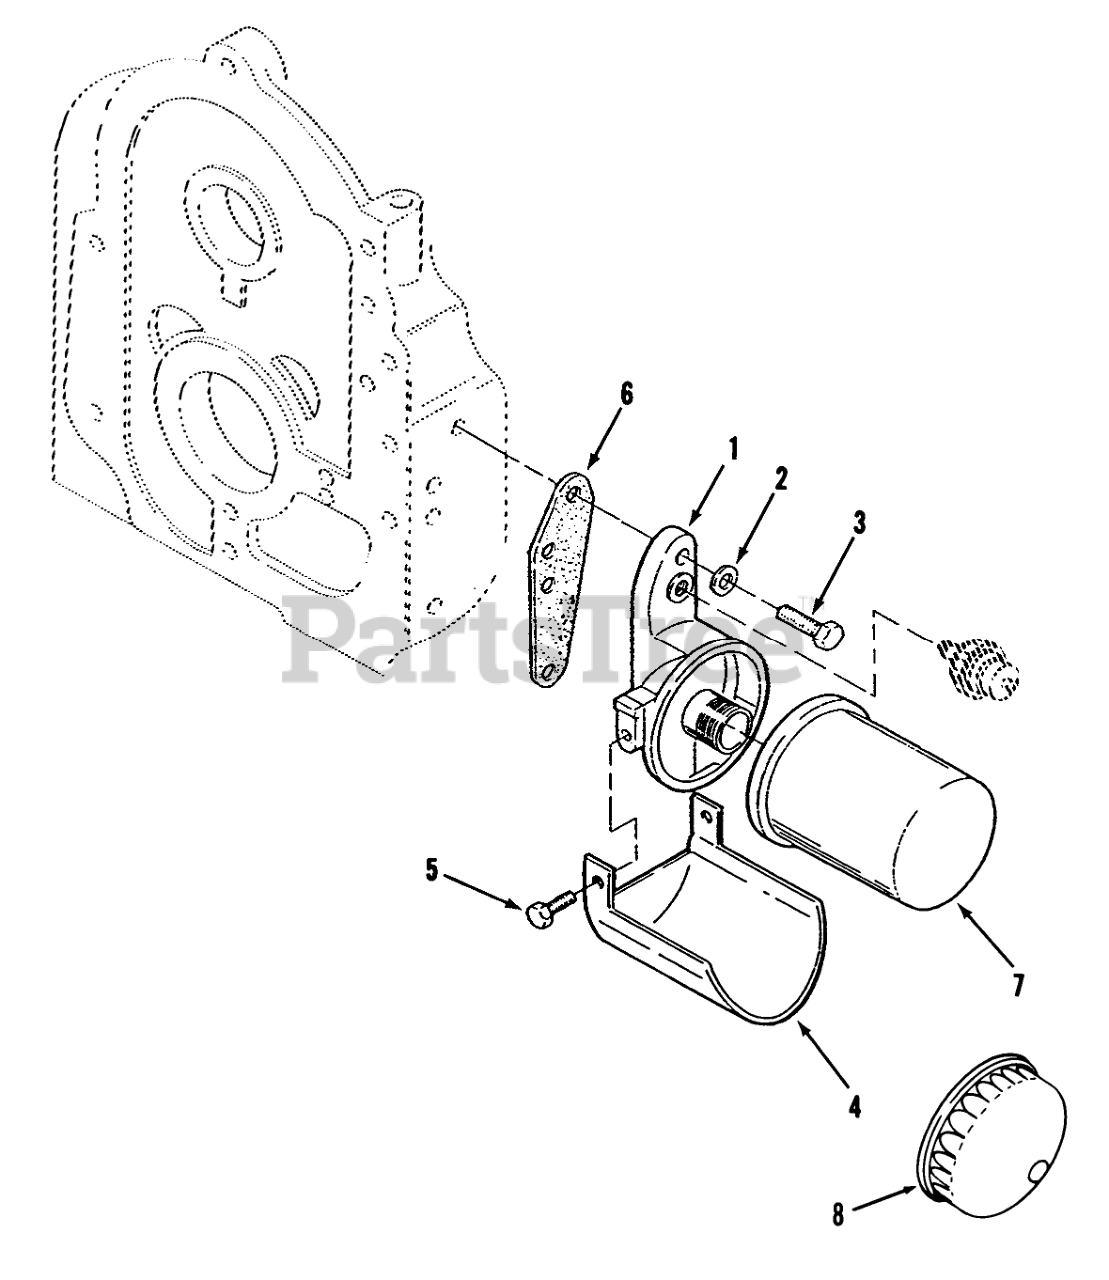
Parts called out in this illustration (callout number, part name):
1	Adapter
2	Washer
3	HHCS 5/16-18 X 1
4	Oil Filter Drain
5	Bolt
6	Gasket
7	Oil Filter
8	Oil Filter Wrench
